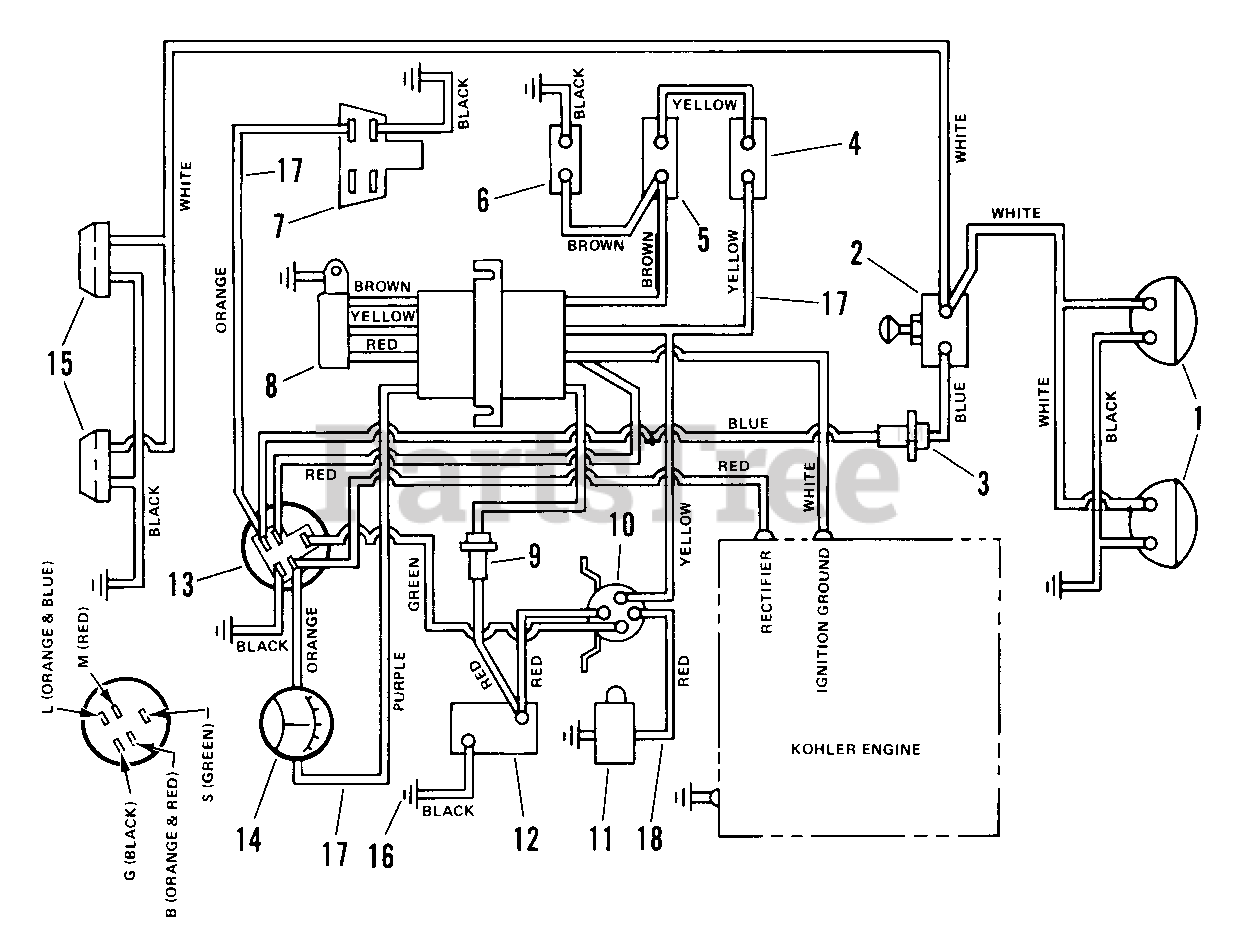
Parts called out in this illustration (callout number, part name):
1	HEAD LIGHT SYSTEM
1	GRILL & LENS ASSEMBLY
1	HEADLIGHT BULB, 1156
2	LIGHT SWITCH ASSEMBLY
2	LIGHT SWITCH
2	PUSH/PULL CONTROL KNOB
4	SWITCH INTERLOCK
5	SWITCH-NEUTRAL START N.O.
6	SWITCH SEAT
7	ACCESSORY CONNECTOR
8	MODULE
10	SOLENOID
11	STARTER MOTOR
12	BATTERY
13	SWITCH ASSEMBLY
14	AMMETER
15	RIGHT TAIL LIGHT
15	LEFT TAIL LIGHT
15	#168 WEDGE BASE BULB
16	GROUND CABLE .25X6.50X.31
17	WIRING HARNESS
18	STARTER CABLE 6.75"
